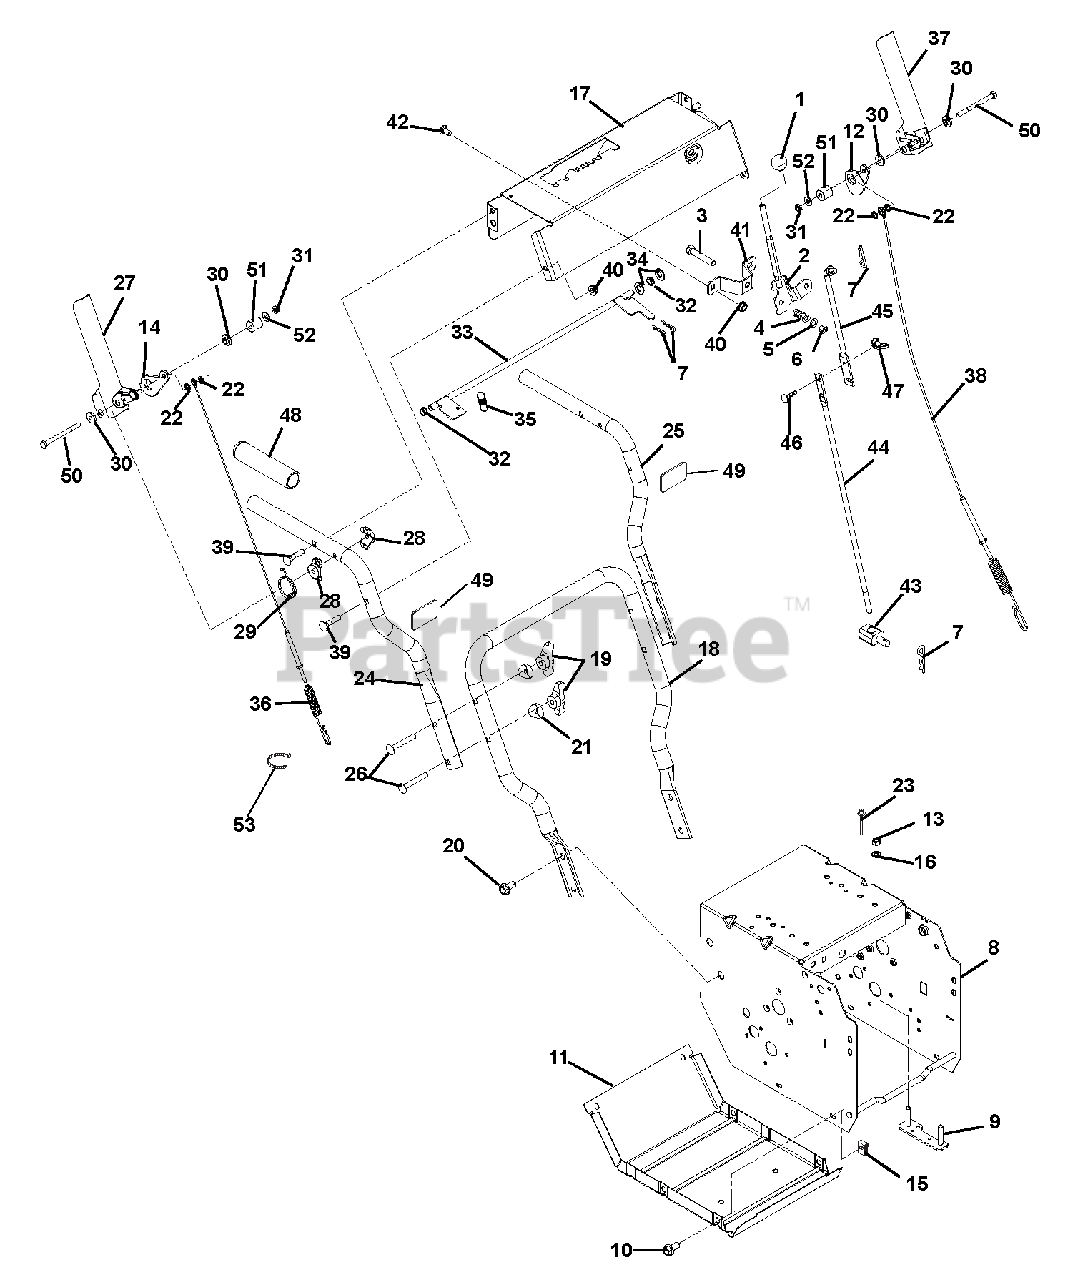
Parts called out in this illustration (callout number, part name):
1	KNOB,BALL -BLACK 1.47" .375-16
2	WMT, SHIFT LEVER
3	@BLT-HEX .38-16X2.00 GR5 YWZC
4	SG-COMP .125X.781X1.250
5	@WSHR-FL-STL.438X1.00X.083 YWZ
6	@NUT-LK-CTR .38-16 YWZC
7	PIN-HAIR INT .08X.18X1.18 YWZC
8	FRAME, MAIN
9	STRAP, ENGINE BOLT-WELDMENT
10	BLT-HEX .25-20X.75 HWH YZ GR5
11	COVER, BOTTOM
12	LH CAM, INTERLOCK
13	@NUT-HEX .31-18 YWZC
14	RH CAM, INTERLOCK
15	NUT-RTNR .25-20X.56
16	WSHR-LK .312X.097 HVY YWZC
17	CONTROL PANEL W/DECAL
18	HANDLEBAR, LOWER - DELUXE
19	KNOB - WING .312-18 UNC
20	BLT-SERHFWH .38-16X.75 YWZC
21	SPACER, HANDLEBAR
22	RG-RTNG-EXT .250X.010
23	RVT-POP .187 YZ
24	HANDLEBAR, UPPER - RH COMP/DEL
25	HANDLEBAR, UPPER - LH COMP/DEL
26	@BLT-RDHDSQNK .31-18X2.25 G5YZ
27	PADDLE, CLUTCH - RH COMPACT
28	SPACER, HANDLEBAR
29	SPRING, TORSION
30	BSHG, FLG .266X.42X.150 PM
31	NUT-JAM-NYL .250-20 W/INSERTYZ
32	BUSHING, POLYLINER-.38 SNAPIN
33	WMT,INTERLOCK SHAFT
34	@WSHR-FL-STL.406X.812X.065 YWZ
35	SPRING, EXTENSION
36	CABLE, ATTACHMENT
37	PADDLE, CLUTCH - LH COMPACT
38	CABLE, TRACTION - DELUXE
39	BLT-RDHDXLSQNK .31-18X1.5 G5YZ
40	@NUT-LK-TOP-FLG .31-18 YWZC
41	BRACKET, SHIFT MOUNT
42	@BLT-RHDSSQNK .31-18X.62 G5YZ
43	PIVOT,SHIFT ROD .375-16(TRUNN)
44	ROD, SHIFT - LOWER
45	ROD, SHIFT - UPPER
46	@BLT-RDHDSQNK .25-20X.75 G5YZ
47	NUT-LK WING .250-20 YWZC
48	HANDLE GRIP
49	BUMPER PAD
50	@BLT-HEX .25-20X3.25 YWZC
51	BSHG, SLV .266 X .750 X .750
52	@WSHR-FL-STL.281X.62X.065 YWZC
53	CABLE TIE LG 5-1/2
